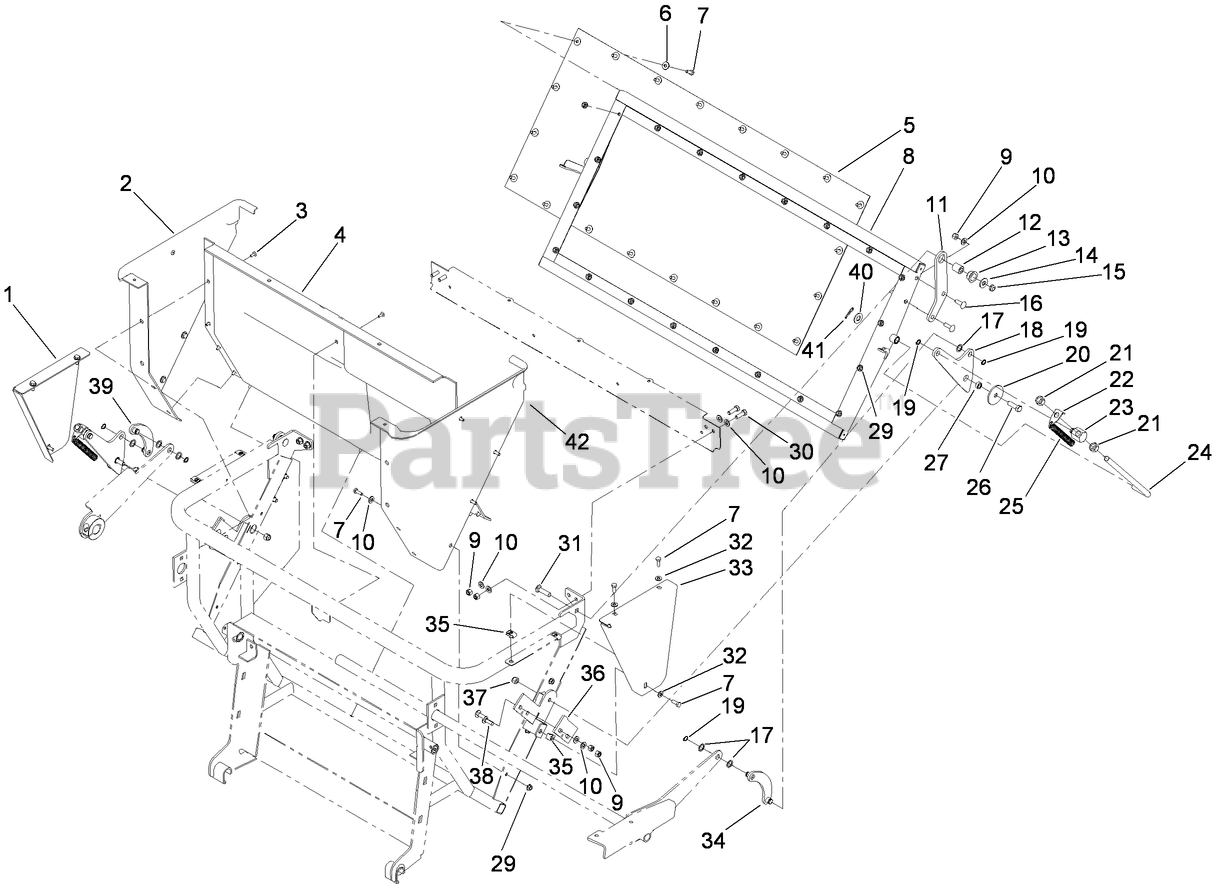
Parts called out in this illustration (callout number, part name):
1	GUARD-RH
2	PANEL-BAGGER, RH
3	RIVET-BLIND
4	PANEL-BAGGER
5	SCREEN-DOOR
6	WASHER-FLAT
7	SCREW-HH
8	DOOR-FRAME
9	NUT-LOCK, NI
10	WASHER-PLAIN
11	PLATE-HINGE
12	PIN-PIVOT, HINGE
13	BEARING
14	WASHER-FLAT
15	NUT-LOCK, NI
16	SCREW-CARR
17	WASHER-NYLON
18	ARM-LINKAGE, DOOR
19	RING-RETAINING
20	WASHER
21	NUT-HEX
22	ANCHOR-SPRING
23	TRUNNION-LINK
24	LINK-DOOR
25	SPRING
26	SCREW-HH
27	BEARING-LINKAGE, PIVOT
29	NUT-HF
30	SCREW-HH
31	SCREW-CARR
32	WASHER-FLAT
33	GUARD-LH
34	LINK-LH
36	STOP-LINKAGE
37	NUT-LOCK, NI
38	BOLT-CARR
39	LINK-RH
40	WASHER-FLAT
41	PIN-COTTER
42	PANEL-BAGGER, LH
